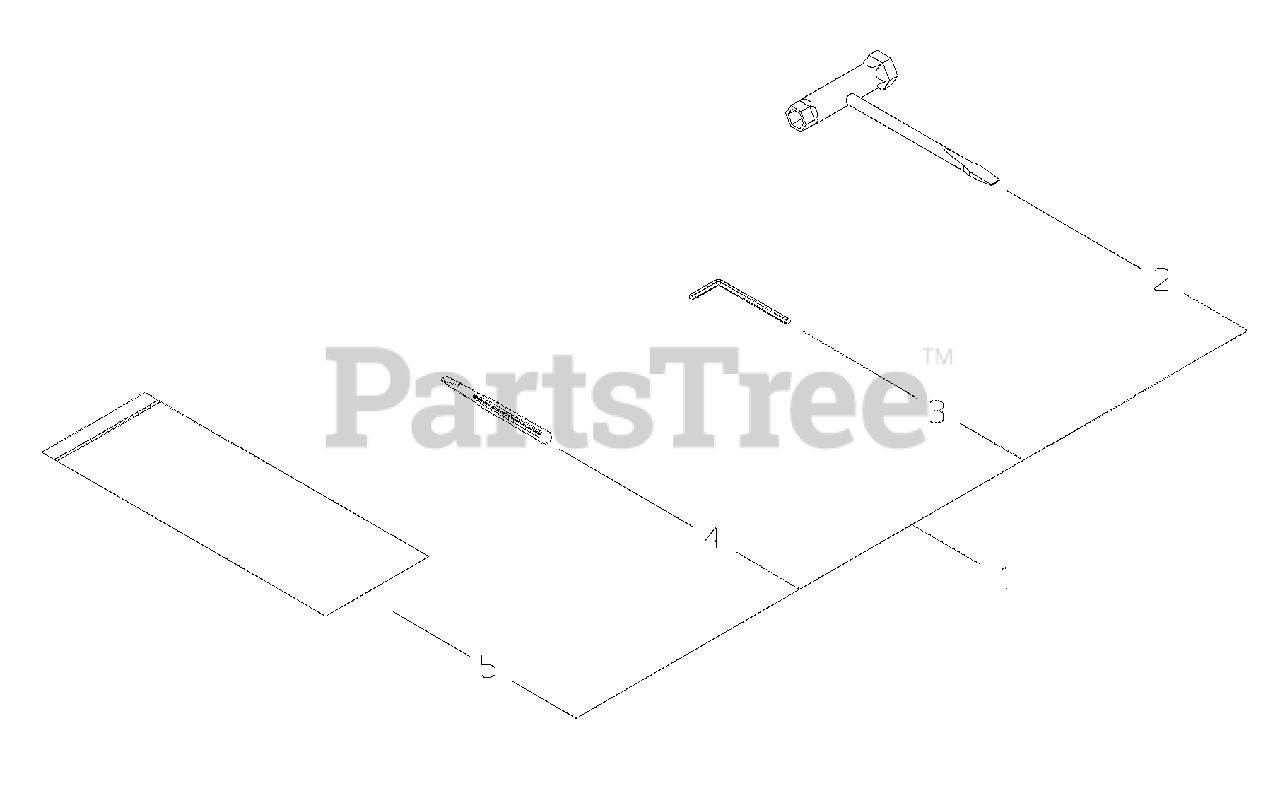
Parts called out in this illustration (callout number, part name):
1	TOOL KIT
2	T-WRENCH - 13X19mm
3	HEX KEY - 4mm
4	SCREWDRIVER - PLASTIC
5	BAG, TOOL
